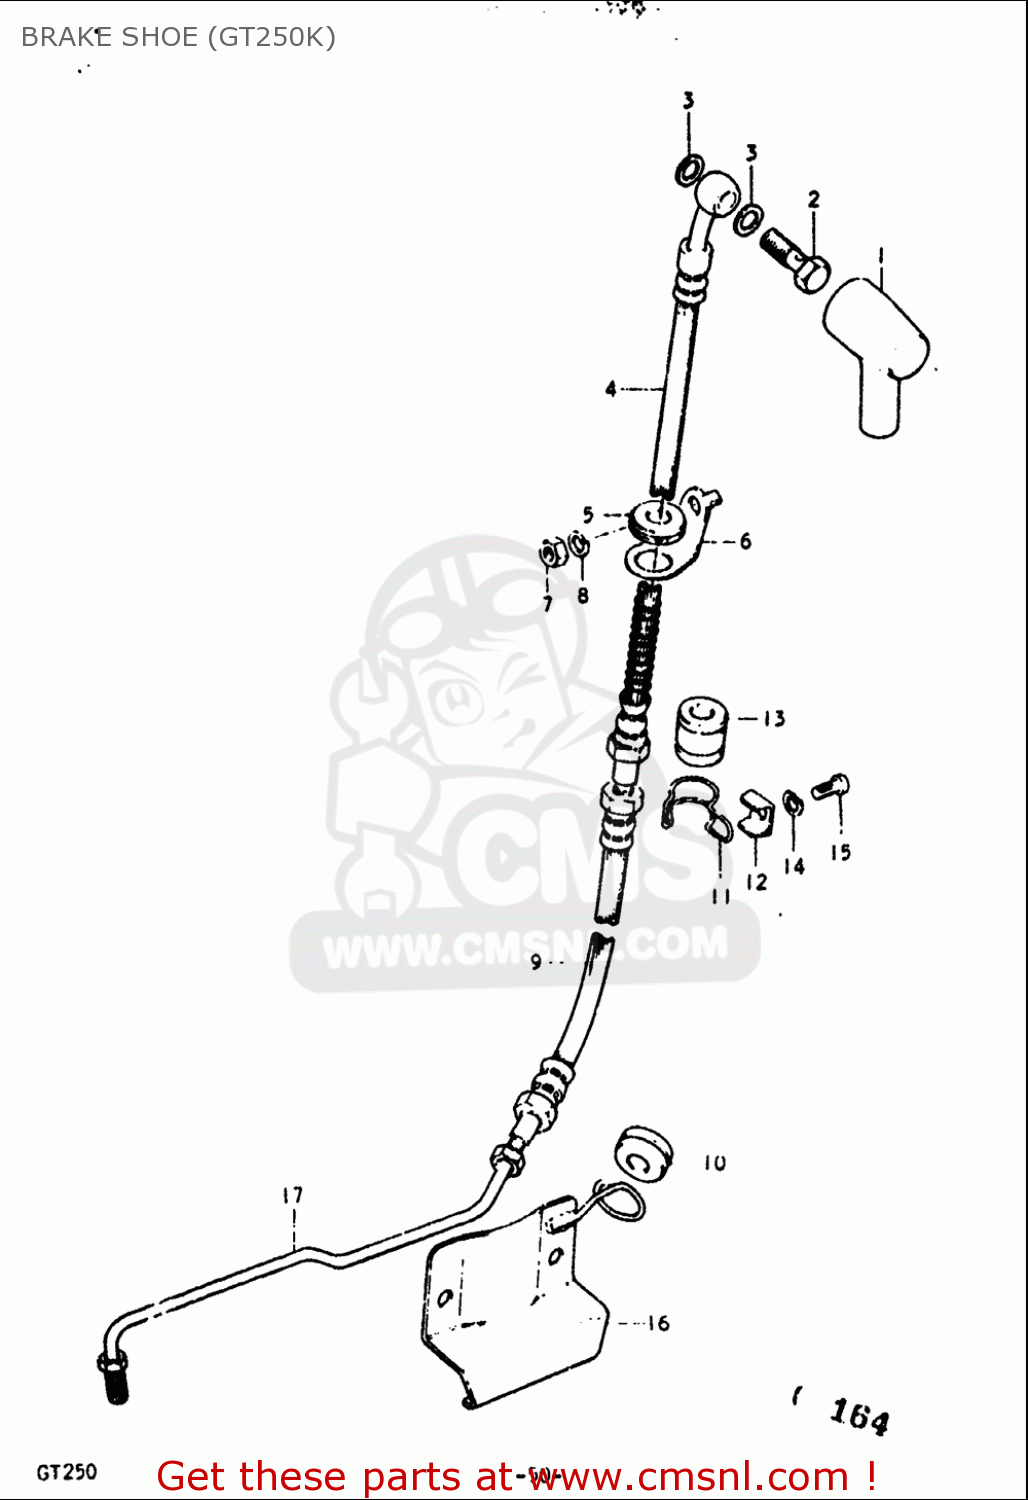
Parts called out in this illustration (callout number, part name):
1	BOOT,MASTER CYLINDER
2	BOLT UNION
3	WASHER(10X15X1.5)
5	GROMMET
7	NUT
8	WASHER,LOCK
14	WASHER,LOCK
15	SCREW(6X12)
